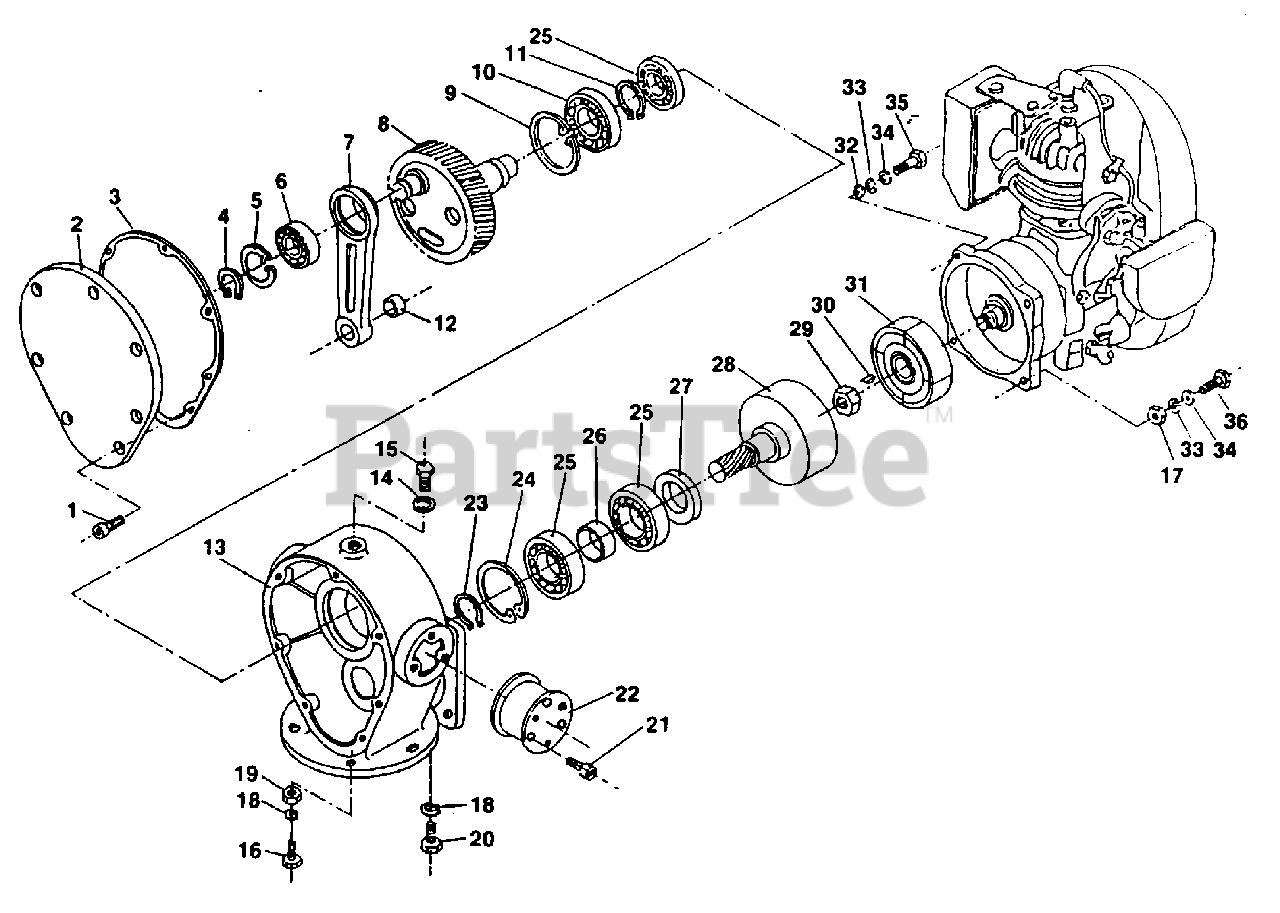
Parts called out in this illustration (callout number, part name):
1	BOLT- Hex m6 x 15
2	COVER- Crank Case
4	RING- Stop (S-17)
5	RING- Stop (H-40)
7	ROD- Connecting
8	GEAR- Crank
9	RING- Stop (H-72)
11	RING- Stop (S-35)
13	CRANKCASE
14	WASHER- Plate m14
15	BOLT- Hex m14 x 16
16	BOLT- Hex m8 x 35
17	NUT- Hex m10
18	WASHER- Spring m8
19	NUT- Nylon m8
20	BOLT- Hex m8 x 25
21	BOLT- Hex m10 x 20
22	RUBBER- Vibration
23	RING- Stop (S-25)
24	RING- Stop (H-52)
27	SEAL- Oil
28	DRUM- Piston Gear
29	NUT- Hex m12 x 1.25
31	CLUTCH- Centrifugal
32	NUT- Nylon m10
33	WASHER- Spring m10
34	WASHER- Plate m10
35	BOLT- Hex m10 x 45
36	BOLT- Hex m10 x 35
